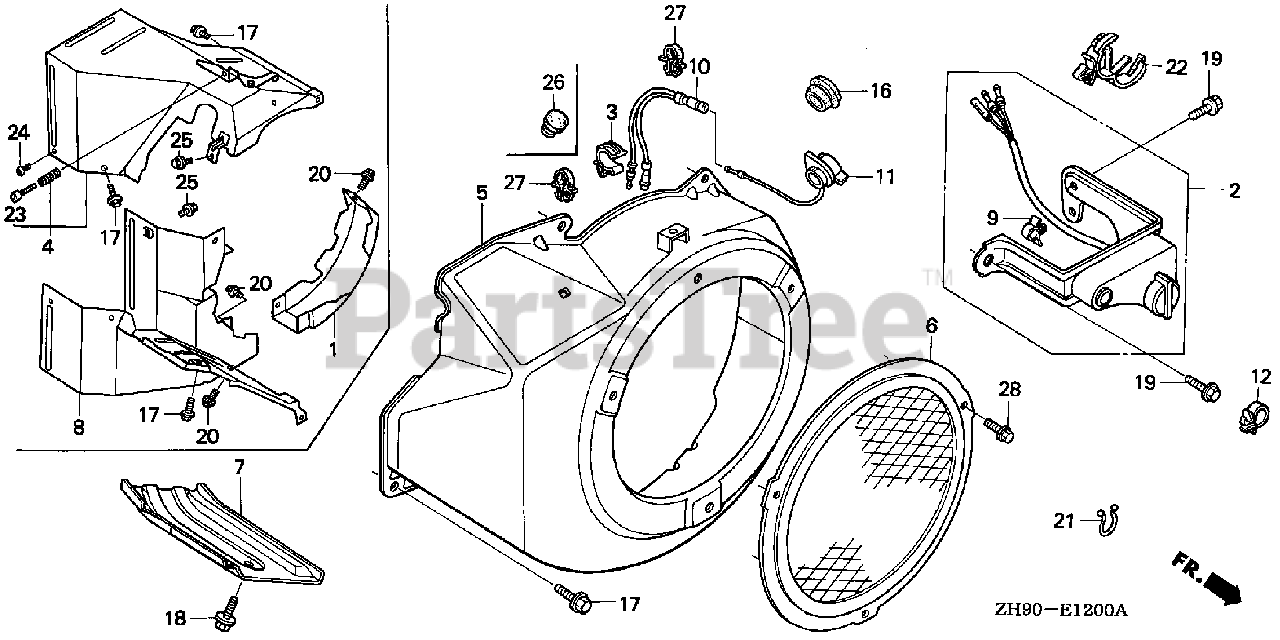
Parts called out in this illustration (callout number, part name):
3	CLIP, TUBE
5	COVER, FAN *NH1* (BLACK)
7	SHROUD
11	SWITCH ASSY., ENGINE STOP
17	BOLT, FLANGE (6X12) (CT200)
18	BOLT, FLANGE (6X12) (CT200)
22	CLIP, WIRE HARNESS
